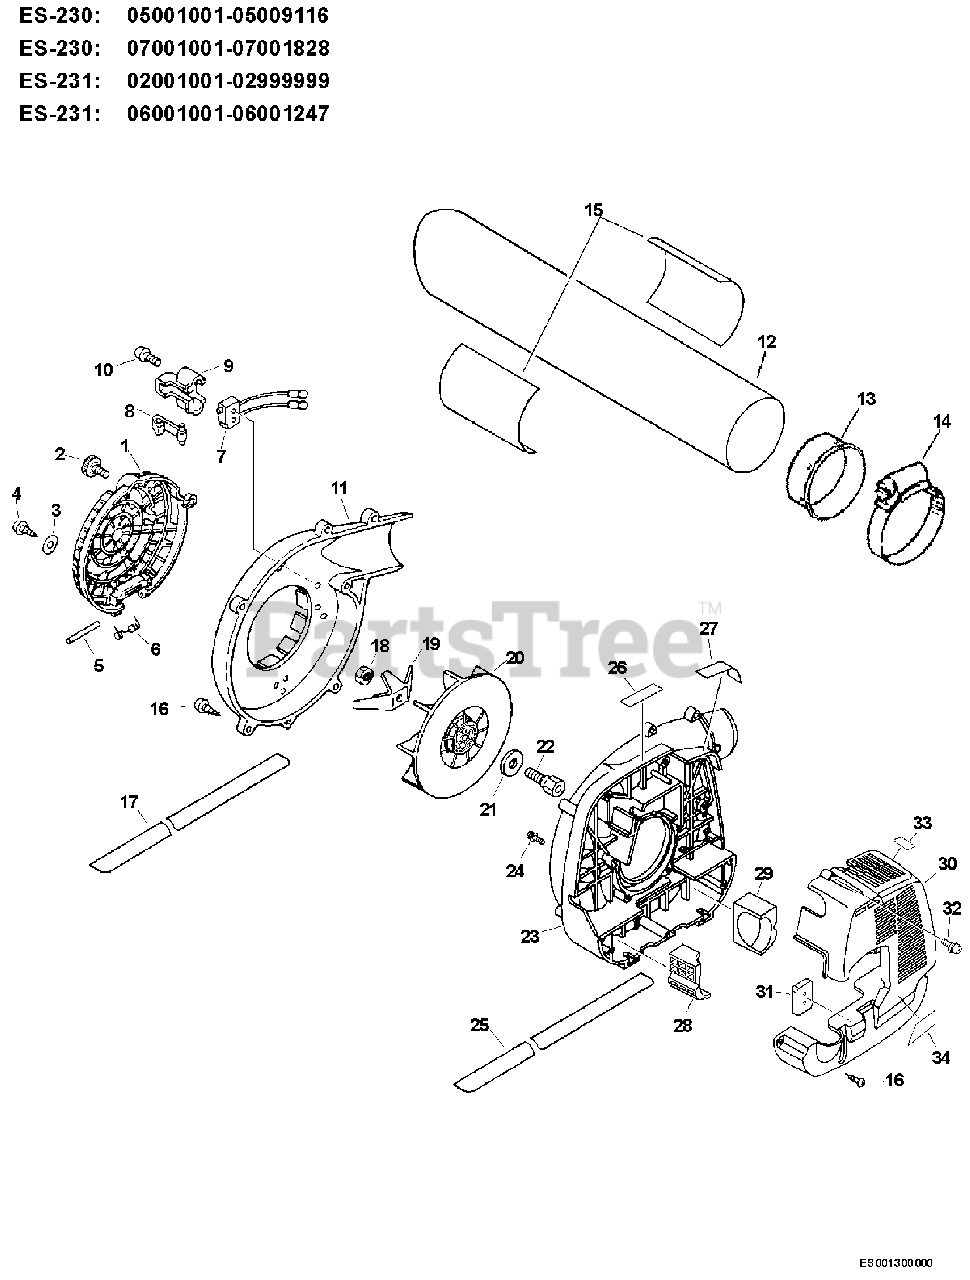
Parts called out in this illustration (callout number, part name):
1	COVER, INTAKE
2	THUMBSCREW
3	WASHER 5.5×12×0.8
4	SCREW 5×14
5	PIN, INTAKE COVER
6	SPRING, COIL
7	SWITCH, INTERLOCK
8	LEVER, SHUT OFF ACTUATOR
9	BRACKET, SWITCH
10	SCREW 4×22
11	COVER, FAN - LEFT
12	TUBE, VACUUM
15	LABEL - SHRED 'N' VAC
16	SCREW, TAPPING 5×20
17	CUSHION
19	SHREDDER
22	HUB, FAN
23	FAN CASE ASSY - INNER
24	SCREW 5×20
25	CUSHION
26	LABEL, NOISE - 70DB(A) CAT. II
27	LABEL, CAUTION - ISO
28	CUSHION
29	CUSHION
30	COVER, ENGINE
31	CUSHION
32	SCREW 5×20
33	LABEL, CAUTION - HOT
34	LABEL, MODEL
